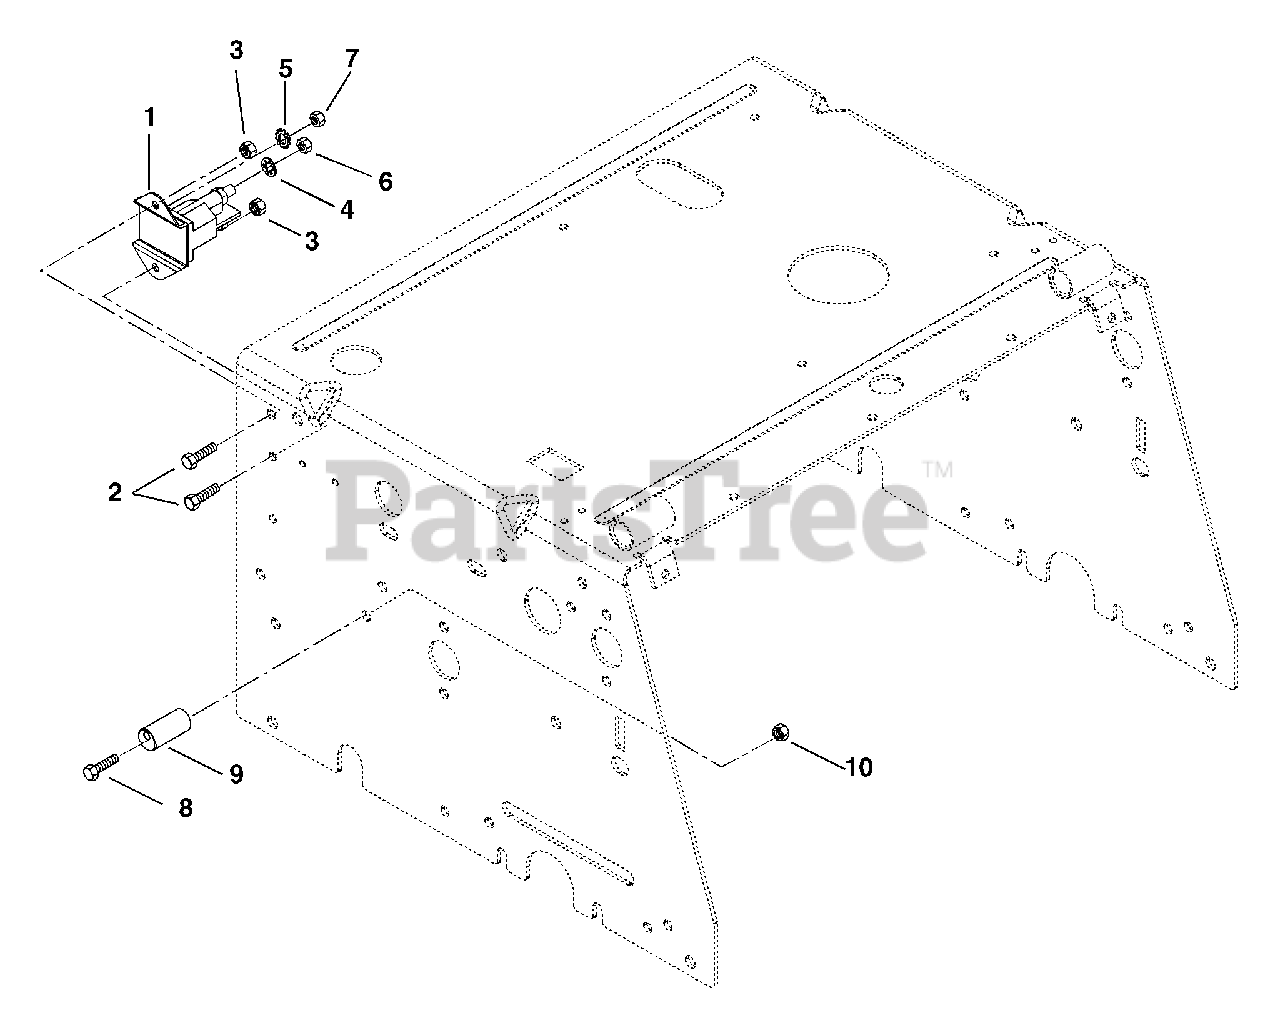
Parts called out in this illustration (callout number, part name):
1	Solenoid
2	Bolt-Hex .25-50 x .50
3	Nut-Locking-Center .25-20 Grade 2
4	Washer-Lock-Internal .31
5	Washer-Lock External #10 I.D. x .022
6	Nut-Jam .312-24
7	Nut 10-32
8	Bolt-Hex .31-18 x 2.75 Grade 5
9	Eccentric
10	Nut-Locking-Nylon .38-18
